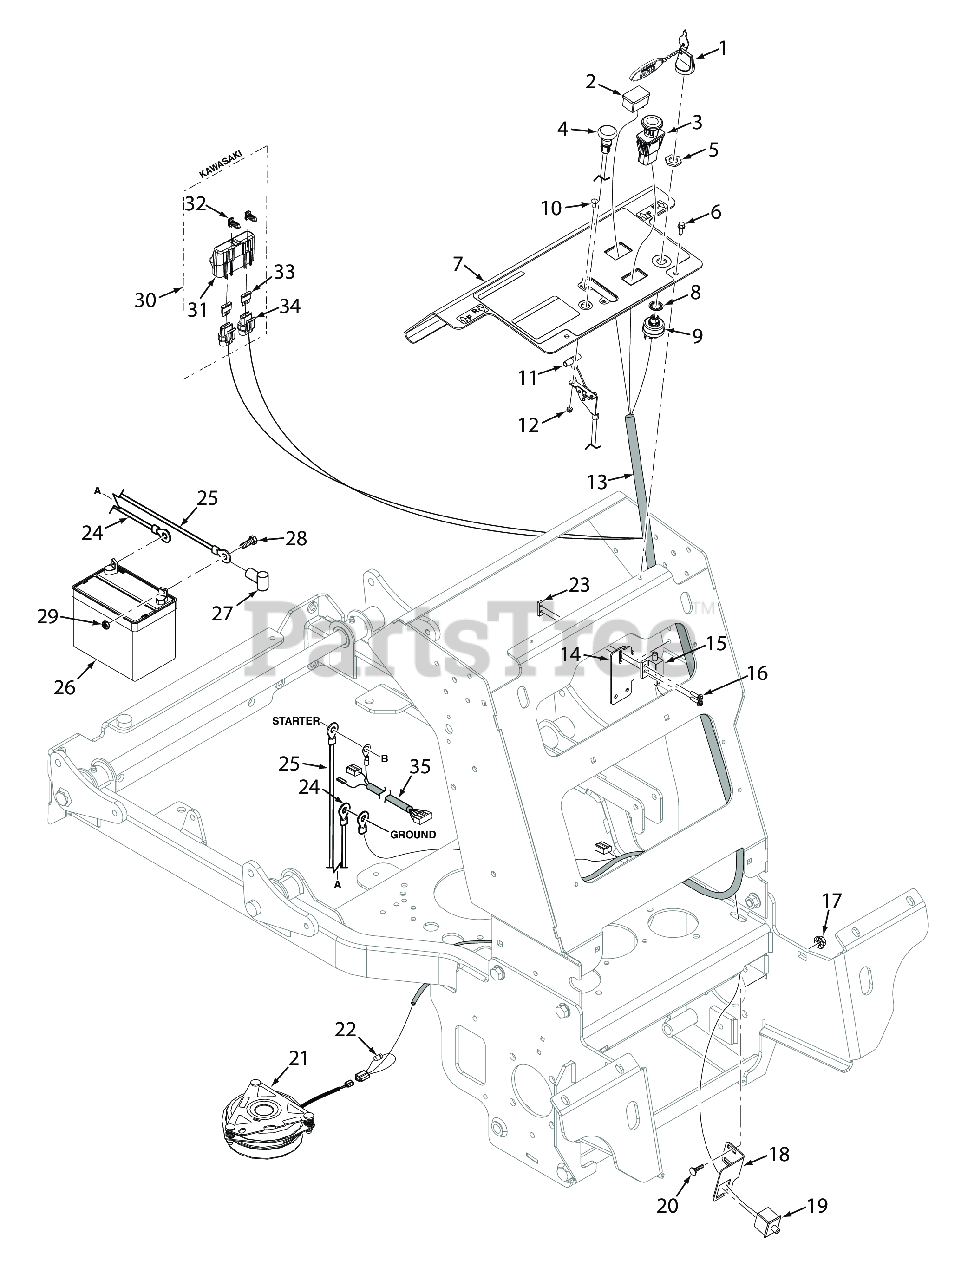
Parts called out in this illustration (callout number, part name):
1	Key, Assembly w/Fob
2	Hour Meter, Inductive
3	Switch, PTO - 10 Amp
4	Choke Control (excludes EFI models)
5	Nut, 5/8-32 Special
6	Screw, Self-Tapping 1/4-20 x 3/4
7	Instrument Panel w/Decal - SVRII36
8	LOCK WASHER, 5/8" INTERNAL TOOTH
9	KEY SWITCH(INCLUDES MOUNTING HARDWARE)
10	Bolt, Carriage #10-24 x 1/2"
11	Throttle Control, SVR
12	Nut, Elastic Stop #10-24
13	Wire Harness, SVRII-36
14	Bracket, Neutral Switch
15	Switch, Interlock (see below)
16	Screw, Hex-Slotted Washer Head #10 32 x 3/4"
17	NUT, 1/4-20 SERRATED FLANGE HEX HEAD
18	Switch Bracket, OPC Switch -SVRII-36
19	Switch, Double Pole OPC - SVRII-36
20	Serr. Fl. Hex Head CPSCR, 1/4-20 x 3/4"
21	Clutch w/Tag GT2.5-FE02 (48 / 52)
22	Diode, 600V 6 Amp
23	Plate, Threaded
24	Battery Cable, 39" Black (26EFI) - Kohler
25	Battery Cable, 44" Red w/Braid (26EFI) - Kohler
26	Battery, 350 CCA (not available through Scag)
27	RUBBER BOOT
28	BOLT, HEX HEAD, 1/4-20 X 3/4 GR.5
29	Nut, 1/4 - 20 Hex
30	Double Fuse Assy.
31	Cover, Sealed Double
32	Clip, Fuse Holder
33	FUSE, 20 AMP BLADE TYPE AUTOMOTIVE
34	Fuse Holder Assembly
35	Adaptor, Wiring Harness (Kawasaki only)
